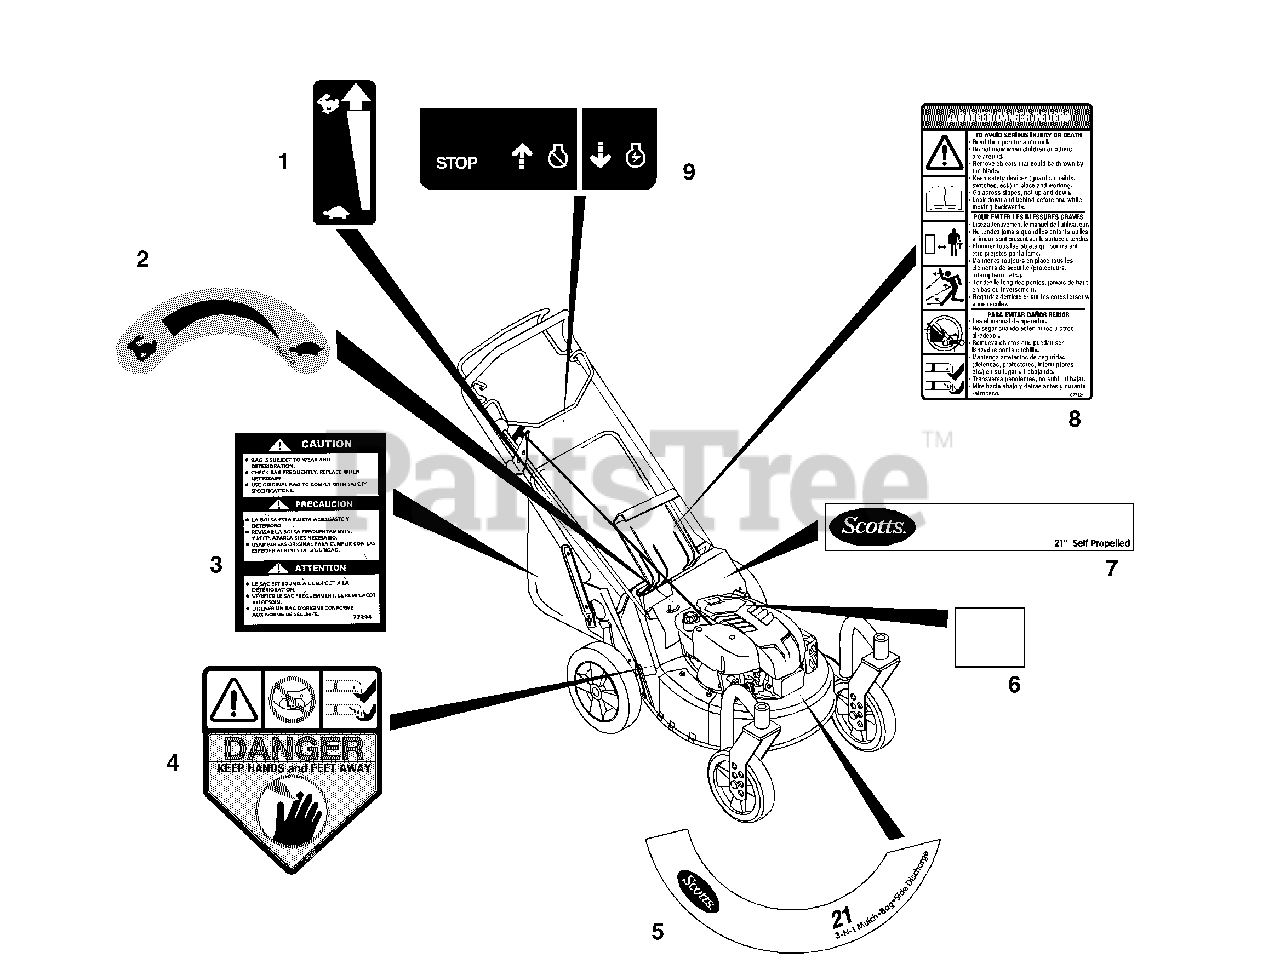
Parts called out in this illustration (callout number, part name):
1	DECAL-SPEED CONTROL
2	DECAL, TURTLE & RABBIT
3	LABEL - BAGGER 21"
4	DECAL, DANGER
5	DECAL, SCOTT'S DECK
6	DECAL, BRIGGS 6.5HP
7	DECAL, SCOTTS DRIVE COVER
8	DECAL, BILINGUAL DANGER
9	DECAL - ENGINE CONTROL
